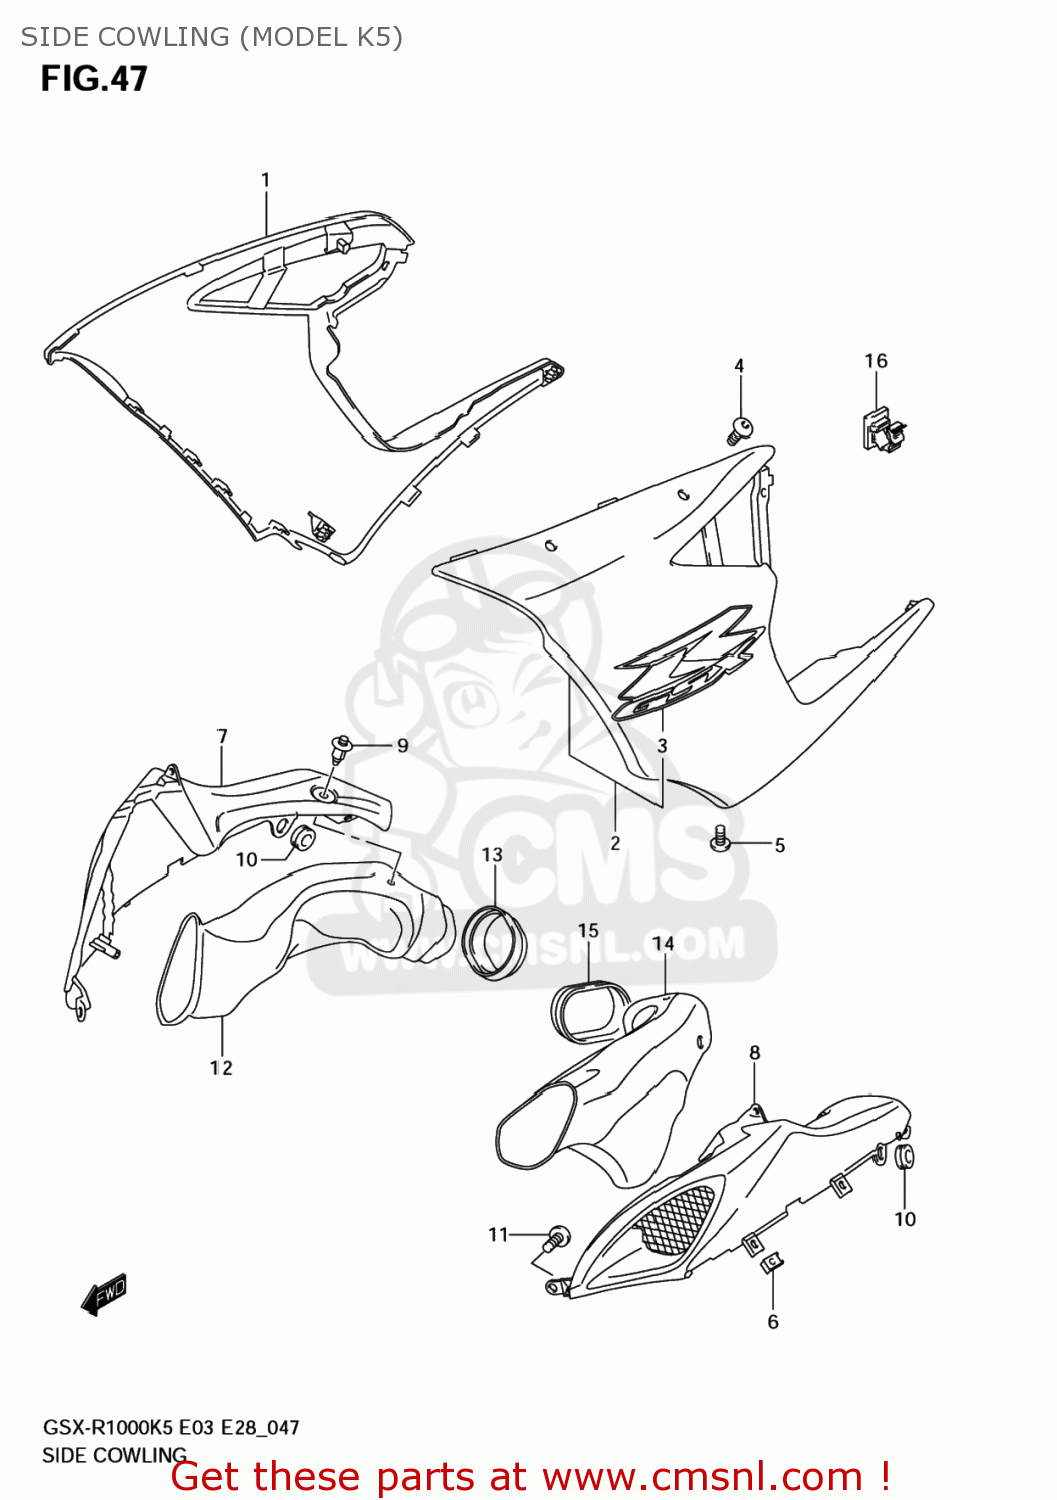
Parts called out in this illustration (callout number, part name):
1	COWLING,SIDE,R
2	COWLING,SIDE,L
3	EMBLEM,GSXR
4	SCREW(5X13)
5	SCREW(5X16)
6	NUT,COWL
7	COVER,INTAKE,R
8	COVER,INTAKE,L
9	CLIP
10	CUSHION
11	SCREW(5X12)
12	PIPE,AIR INTAKE,R
13	MOLDING,AIR INTAKE,R
14	PIPE,AIR INTAKE,L
15	MOLDING,AIR INTAKE,L
16	CLAMP
